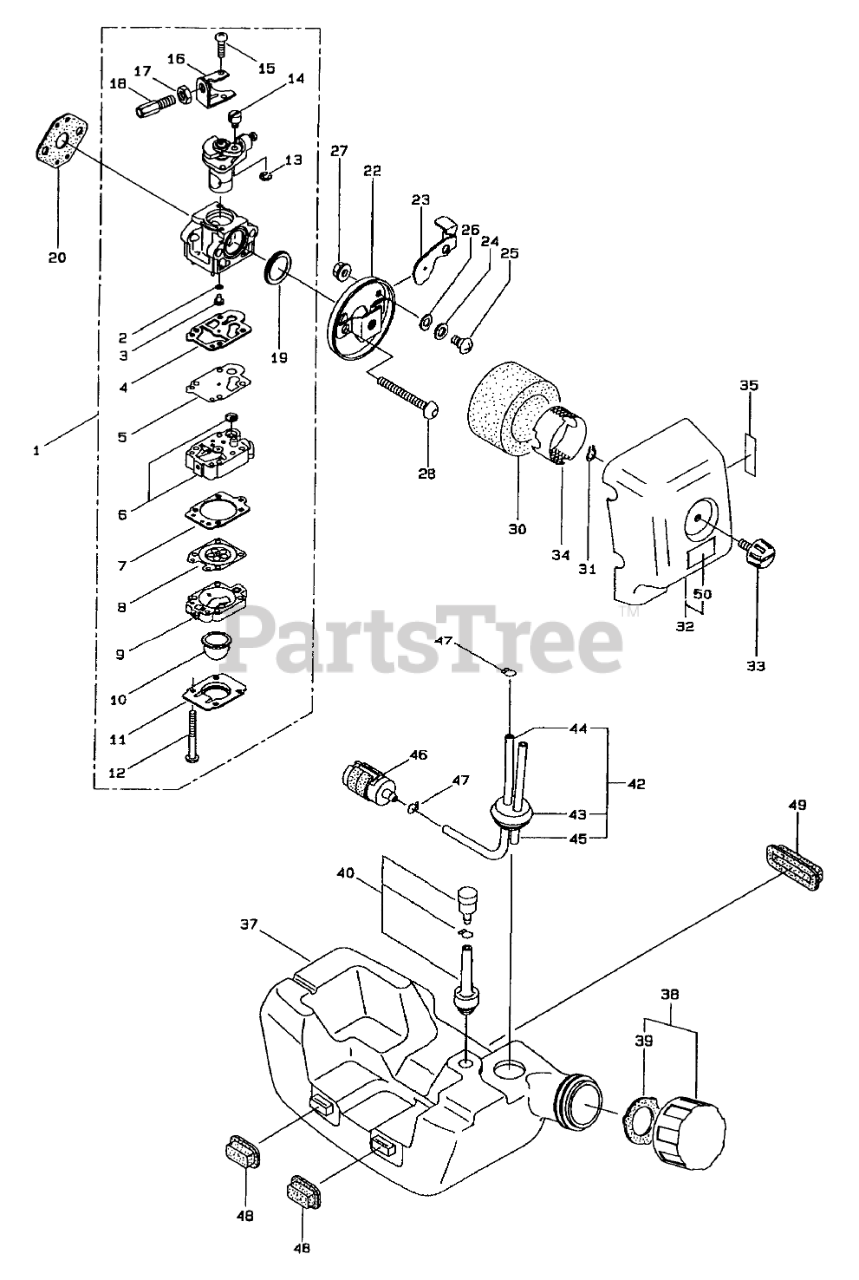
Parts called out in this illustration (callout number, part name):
1	Carburetor Assembly (Incl. Ref. # 2-19)
2	O-RING
3	JET - MAIN #40.5
4	GASKET (NC)
5	PUMP - DIAPHRAGM (NC)
6	PUMP - BODY
7	GASKET (NC)
8	ASM - DIAPHRAGM
9	PURGE - BODY (NC)
10	PRIMER
11	PLATE - COVER (NC)
12	SCREW (NC)
13	E-RING
14	SWIVEL
15	Screw
16	BRACKET
18	ADJUSTER
19	PACKING
20	GASKET
22	BRACKET
23	VALVE - CHOKE
24	PACKING
26	WASHER
30	ELEMENT
32	COVER - AIR FILTER
34	SCREEN
35	LABEL
37	TANK - FUEL
38	Fuel Tank Cap Assembly (Incl. Ref. # 39)
39	PACKING
40	ASM - BREATHER
42	Fuel Pipe Assembly (Incl. Ref. # 42-45)
43	GROMMET
44	PIPE - FUEL
45	PIPE - RETURN
46	ASM - FUEL FILTER
50	DECAL - WARNING
